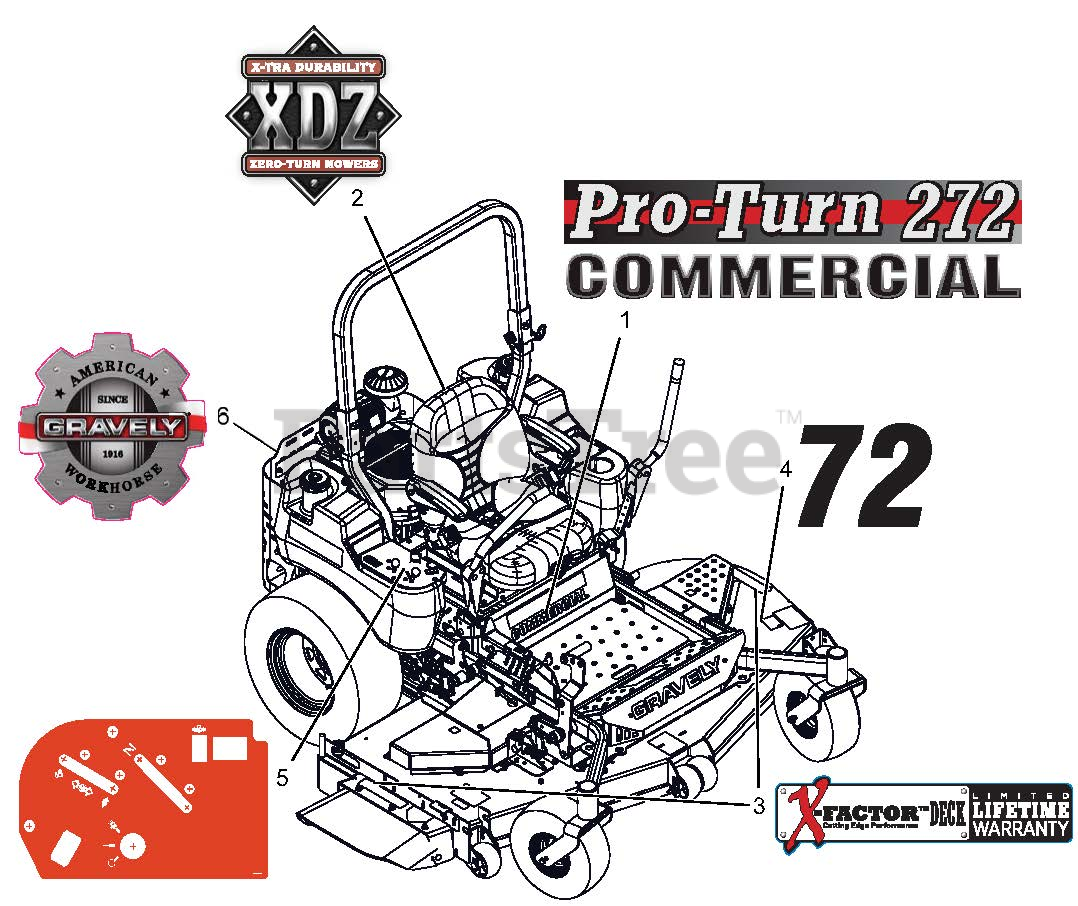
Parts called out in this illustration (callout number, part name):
1	DECAL, PRO-TURN 272
2	DECAL, XDZ 5"
3	DECAL-X-FACTOR DECK
4	DECAL - 72"
5	DECAL, CONTROL PANEL NON EFI
6	DECAL, GRAVELY HERITAGE-LARGE
